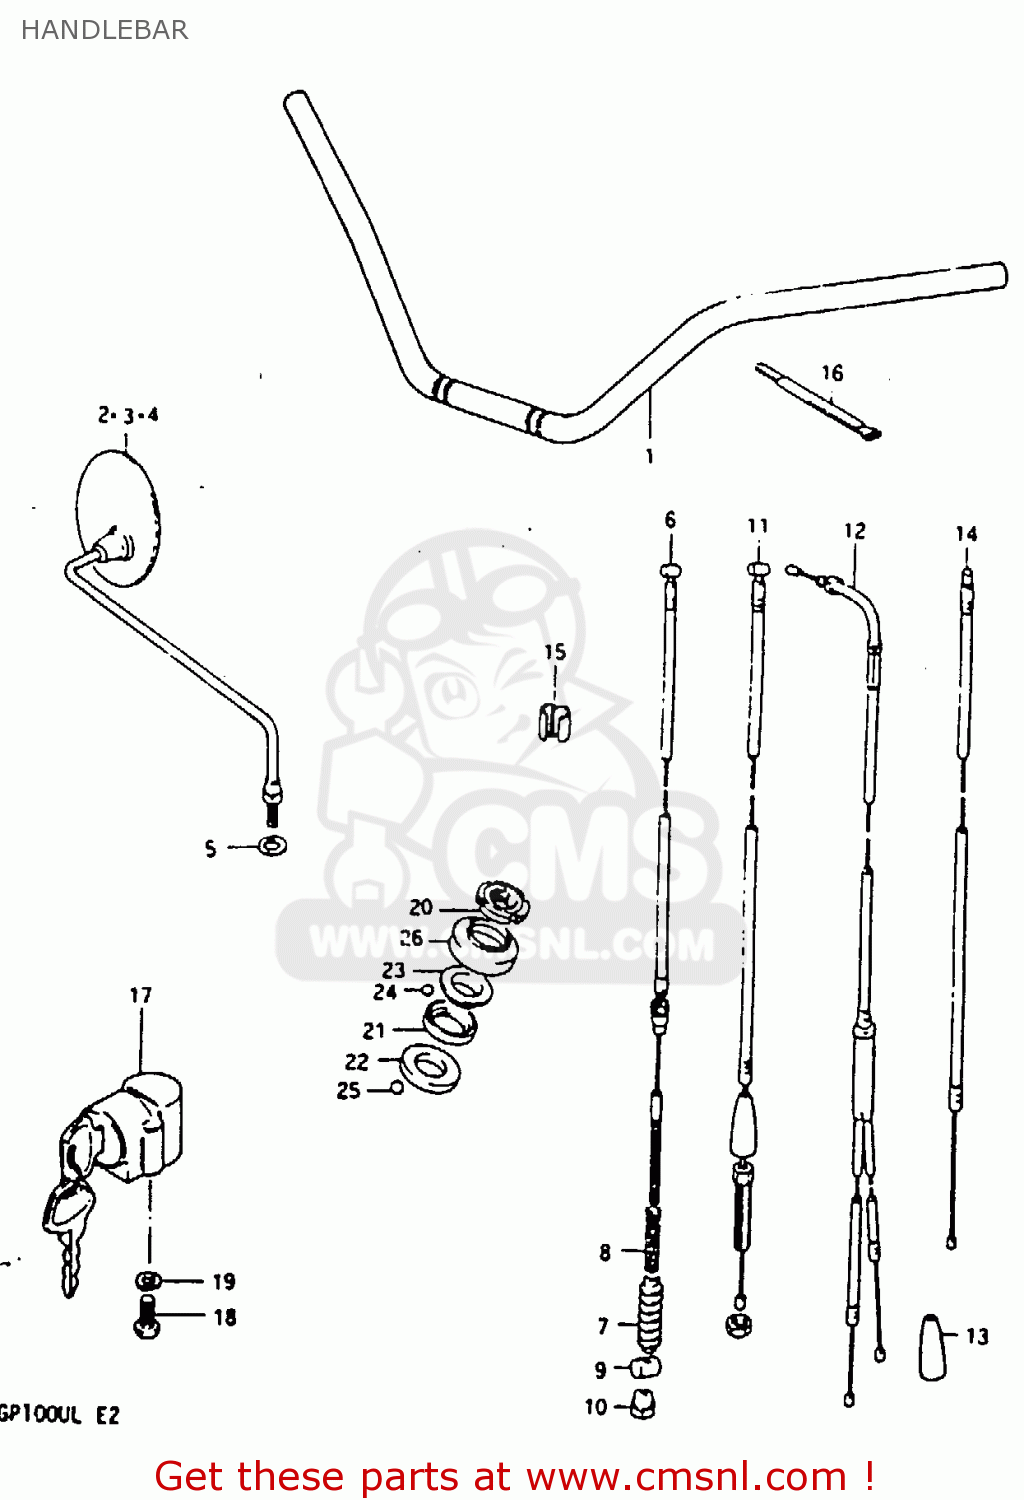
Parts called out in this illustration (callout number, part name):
1	HANDLEBAR
2	MIRROR ASSY, REAR VIEW
3	MIRROR, REAR VIEW RH
4	MIRROR, REAR VIEW LH
5	WASHER
6	CABLE,FR BRAKE
7	SEAL,DUST(7X16X75)
8	SPRING
9	PIN,10X19
10	NUT
11	CABLE ASSY,CLUTCH
12	CABLE ASSY,THROTTLE
13	SEAL,DUST(7X18X30)
14	CABLE STARTER
15	CLIP
16	CLAMP
17	LOCK ASSEMBLY,STEERING
18	SCREW
19	LOCK WASHER
20	NUT,STEERING STEM(25X44X10)
21	RACE,STEERING INNER UPR
22	LACE,STEERING INNER LWR
23	RACE,STEERING OUTER UPR
24	BALL
25	BALL
26	DUST SEAL,STEERING UPR
